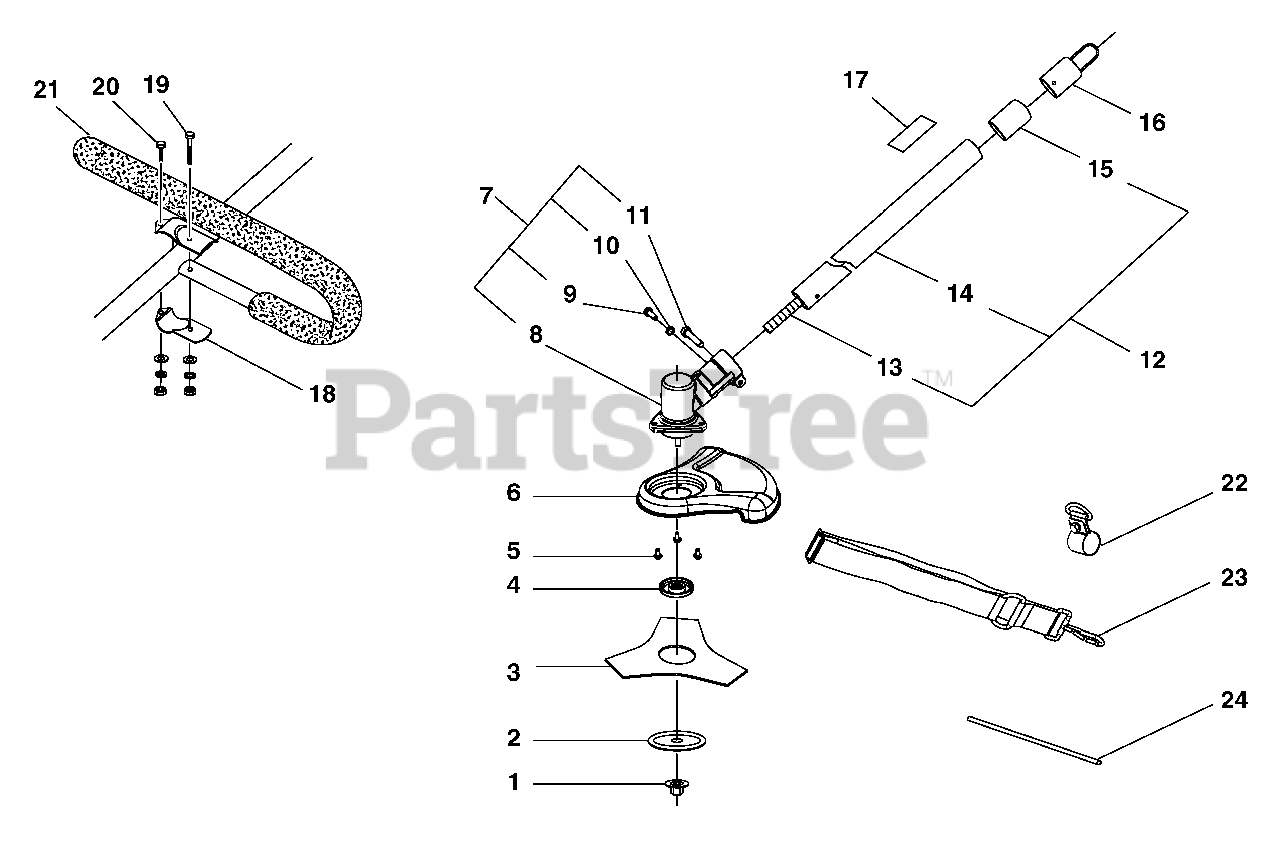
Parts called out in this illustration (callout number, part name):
1	NUT-LOCK(M8)
2	FLANGED WASHER
3	BLADE
4	CUPPED WASHER
5	SCREW-HEX (10-24UNC) WITH DISH WASHER
6	SHIELD
7	GEARHEAD & SCREW ASSEMBLY
8	GEAR HEAD ASSEMBLY
9	HEXAGON HEAD SCREW (M5 X 12 mm)
10	LOCK WASHER
11	CAP HEAD SCREW (M6 X 30 mm)
12	BOOM ASSEMBLY
13	FLEXIBLE SHAFT
14	DRIVE SHAFT HOUSING ASSEMBLY
15	DUST PROOF COVER
16	HANGER
17	WARNING LABEL
18	HANDLE BAR CLAMP
19	BOLT ASSEMBLY (LONG)
20	BOLT ASSEMBLY (SHORT)
21	J-HANDLE AND GRIP
22	STRAP HANGER
23	SHOULDER STRAP ASSEMBLY
24	HOLDING PIN
